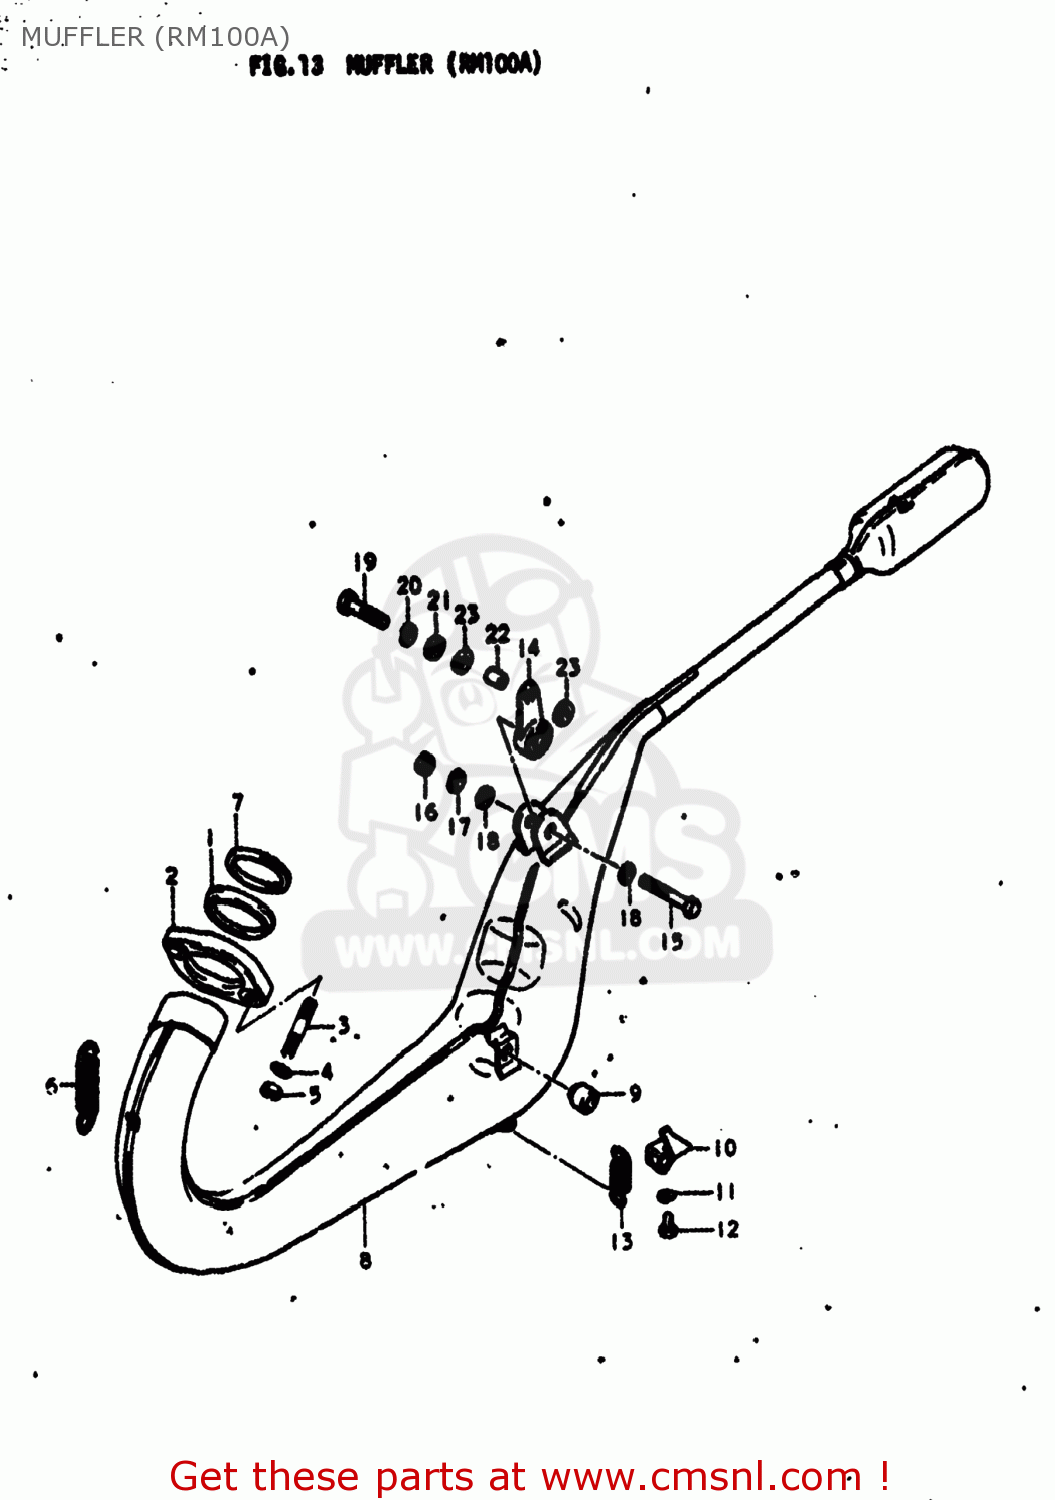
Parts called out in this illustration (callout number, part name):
1	GASKET,EXHAUST PIPE (NAS)
2	CLAMP,EXHAUST PIPE
3	STUD 6X20
4	LOCK WASHER
5	NUT
6	SPRING
7	CUSHION,EXHAUST PIPE
8	BODY,MUFFLER
9	CUSHION(11.5X22X20)
10	BRACKET, MUFFLER STOPPER
11	LOCK WASHER
12	BOLT
13	SPRING
14	DAMPER,MUFFLER SUPPORT
15	** SUPERSEEDED
16	NUT
17	LOCK WASHER
18	WASHER
19	BOLT
20	LOCK WASHER
21	WASHER
22	SPACER (8.6X13.8X9)
23	CUSHION
